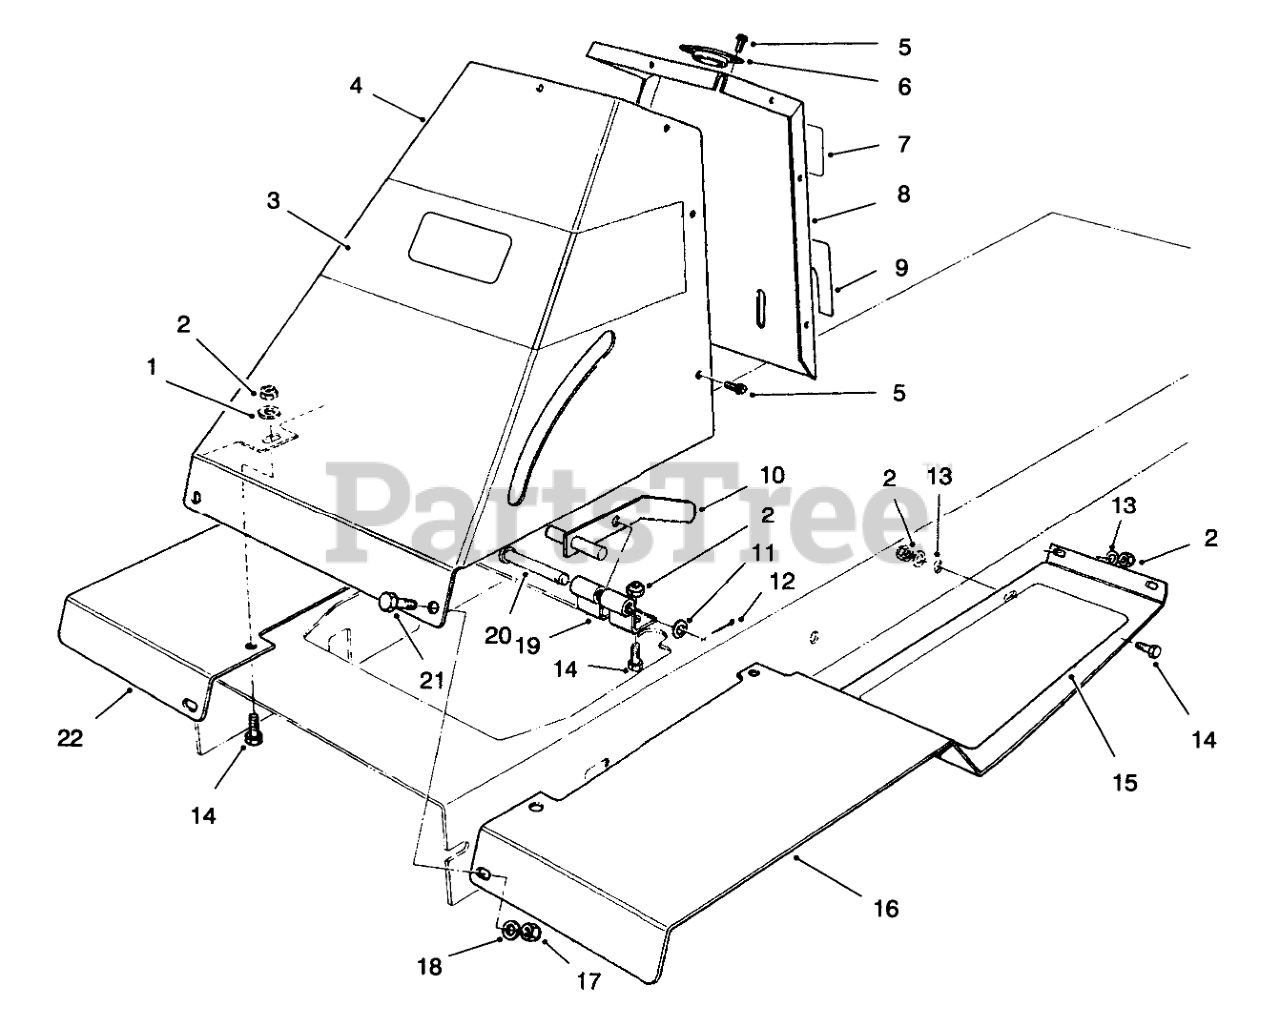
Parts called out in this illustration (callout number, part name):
1	WASHER-FLAT
2	NUT-LOCK, NI
3	DECAL - STEERING SUPT
4	Tower-Front
5	SCREW-HWHTF
6	GUIDE-STRG SHAFT
7	DECAL-DANGER
8	Tower-Rear
9	PARK BRAKE DECAL
10	PARKING BRAKE WA B
11	WASHER-FLAT
12	PIN-COTTER
13	WASHER-PLAIN
14	SCREW-HH
15	TREAD-L.H. FOOT
16	Footrest-LH
17	NUT-LOCK, NI
18	WASHER-FLAT
19	Bracket-Parking Brake
20	PIN-CLEVIS
21	SCREW-HH
22	Footrest-RH.
